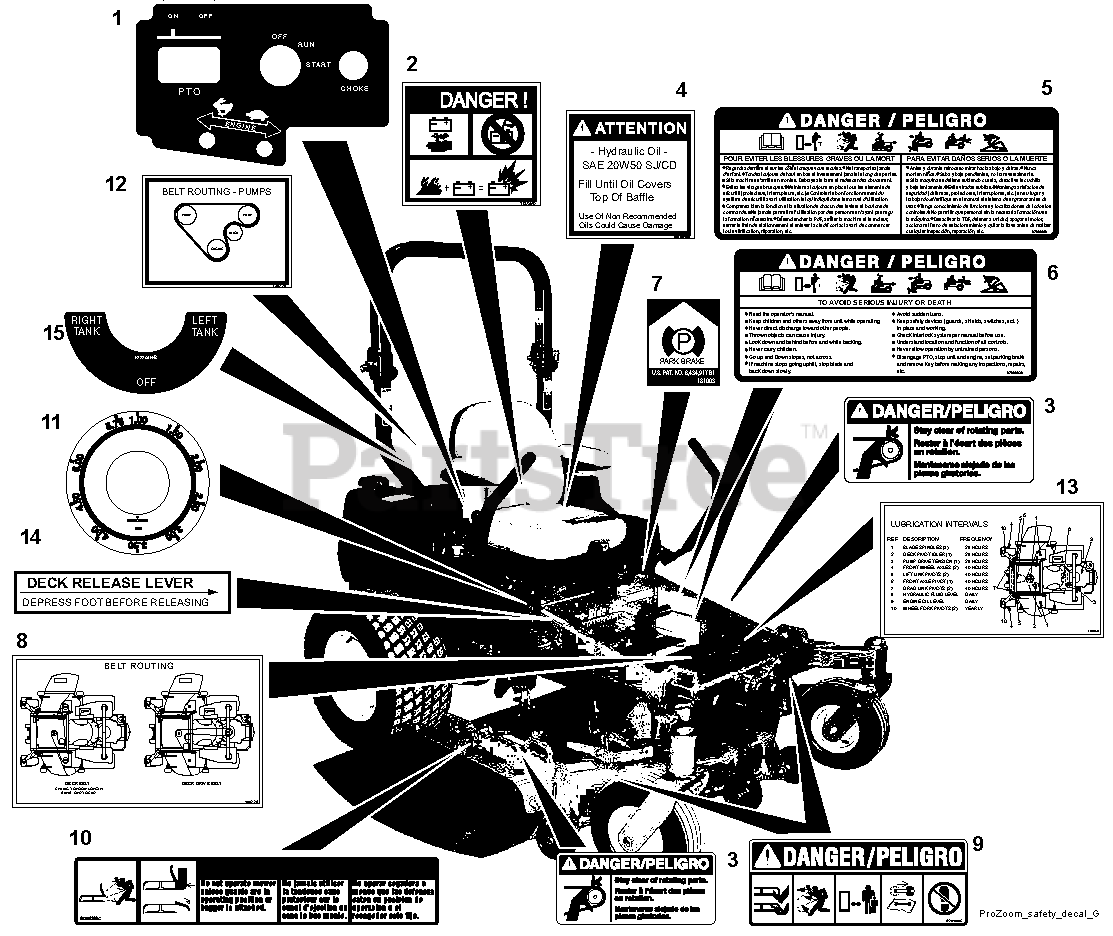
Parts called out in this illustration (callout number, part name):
1	Decal, Control Panel - 03971800 (Serial Number 101 - 2499)
2	Decal, Danger - Battery
3	Decal, Danger Belt Rotation
4	Attention, Hydraulic Reservoir
5	Decal, Safety French/Spanish
6	Decal, Safety English
7	Decal, Park Brake
8	Decal, Belt Routing
9	Decal, Mower Pan Danger
10	Decal, Warning
11	Decal, HOC Index
12	Decal, Pump Belts
13	Decal, Lubrication Intervals
14	Decal, Deck Release Lever
15	Decal, Fuel
